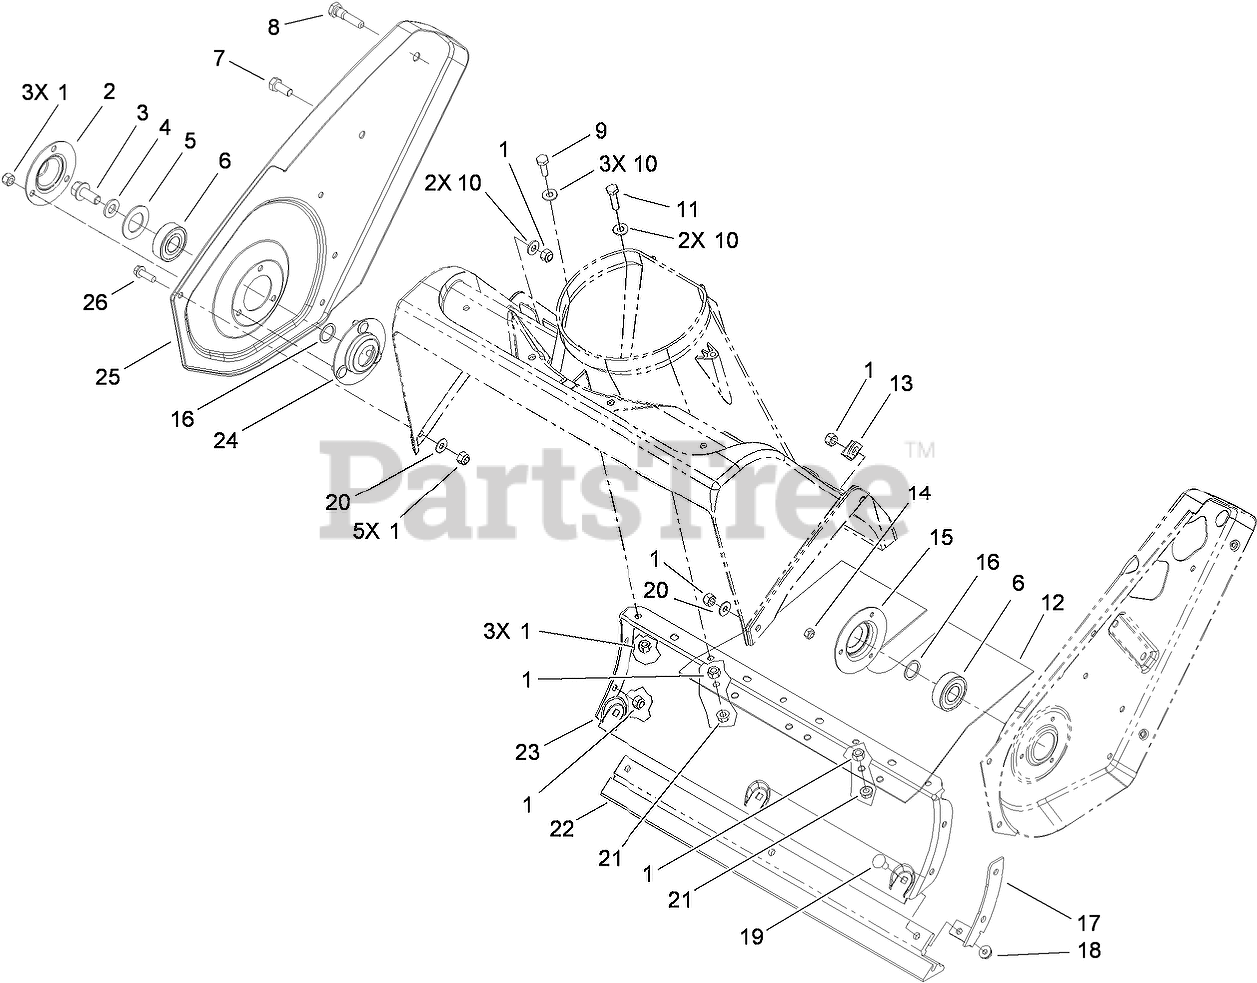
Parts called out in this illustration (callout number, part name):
1	NUT-LOCK, NI
2	RETAINER-BEARING
3	SCREW-HHF
4	WASHER-FLAT
5	WASHER-RUBBER
6	BEARING-BALL
7	SCREW-HH
8	PIN-ROTOR
9	SCREW-HH
10	WASHER-FLAT
11	SCREW-HH
12	COVER-BOTTOM
13	BRACKET-HOUSING
14	NUT-LOCK, NI
15	FLANGE-BEARING
16	WASHER-THRUST
17	BRACKET-HOUSING, LOWER
18	NUT-KEPS
19	SCREW-CARR
20	WASHER-FLAT
21	NUT-LOCK, HHF
22	SCRAPER
23	HOUSING-LOWER
24	FLANGE-BEARING
25	SIDEPLATE-RIGHT
26	SCREW-HWH
